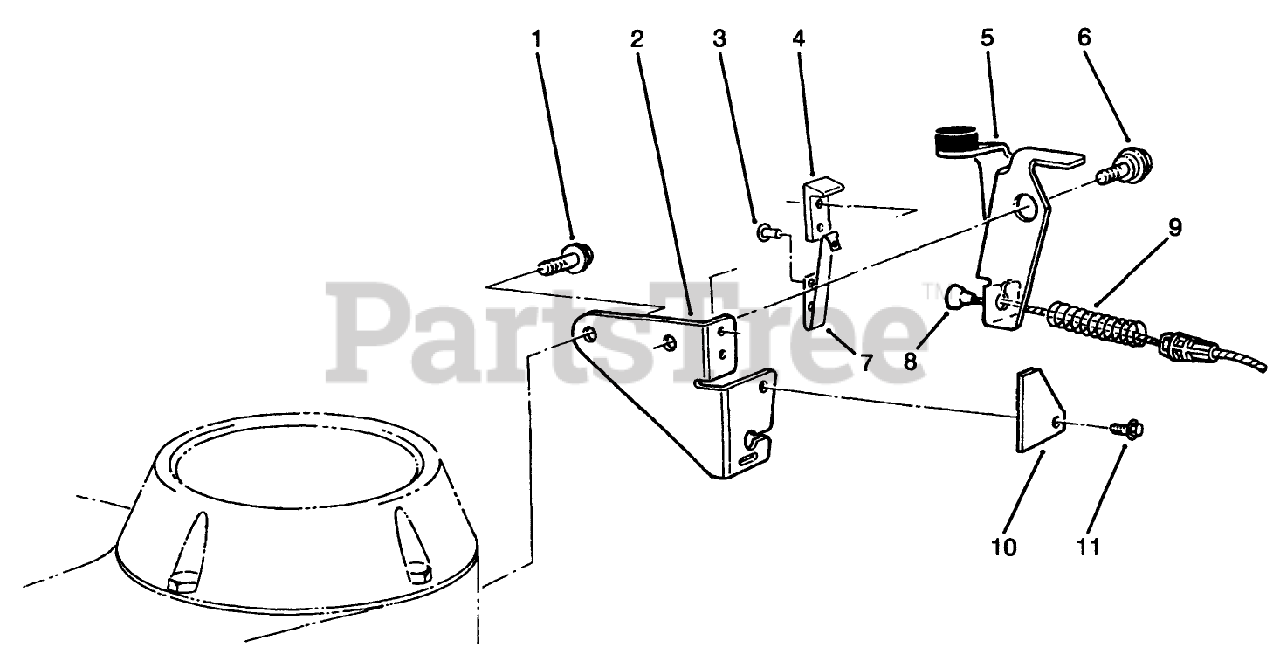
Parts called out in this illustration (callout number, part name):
1	SCREW-HWH
2	PLATE-BRAKE
3	RIVET-PLASTIC
4	STRAP-INSULATING
5	BRAKE PLATE ASM
6	SCREW-SHOULDER
7	STRAP-GROUND
8	BRAKE CABLE
9	SPRING-COMPRESSION
10	STOP-GROUND STRAP
11	SCREW-HWH
